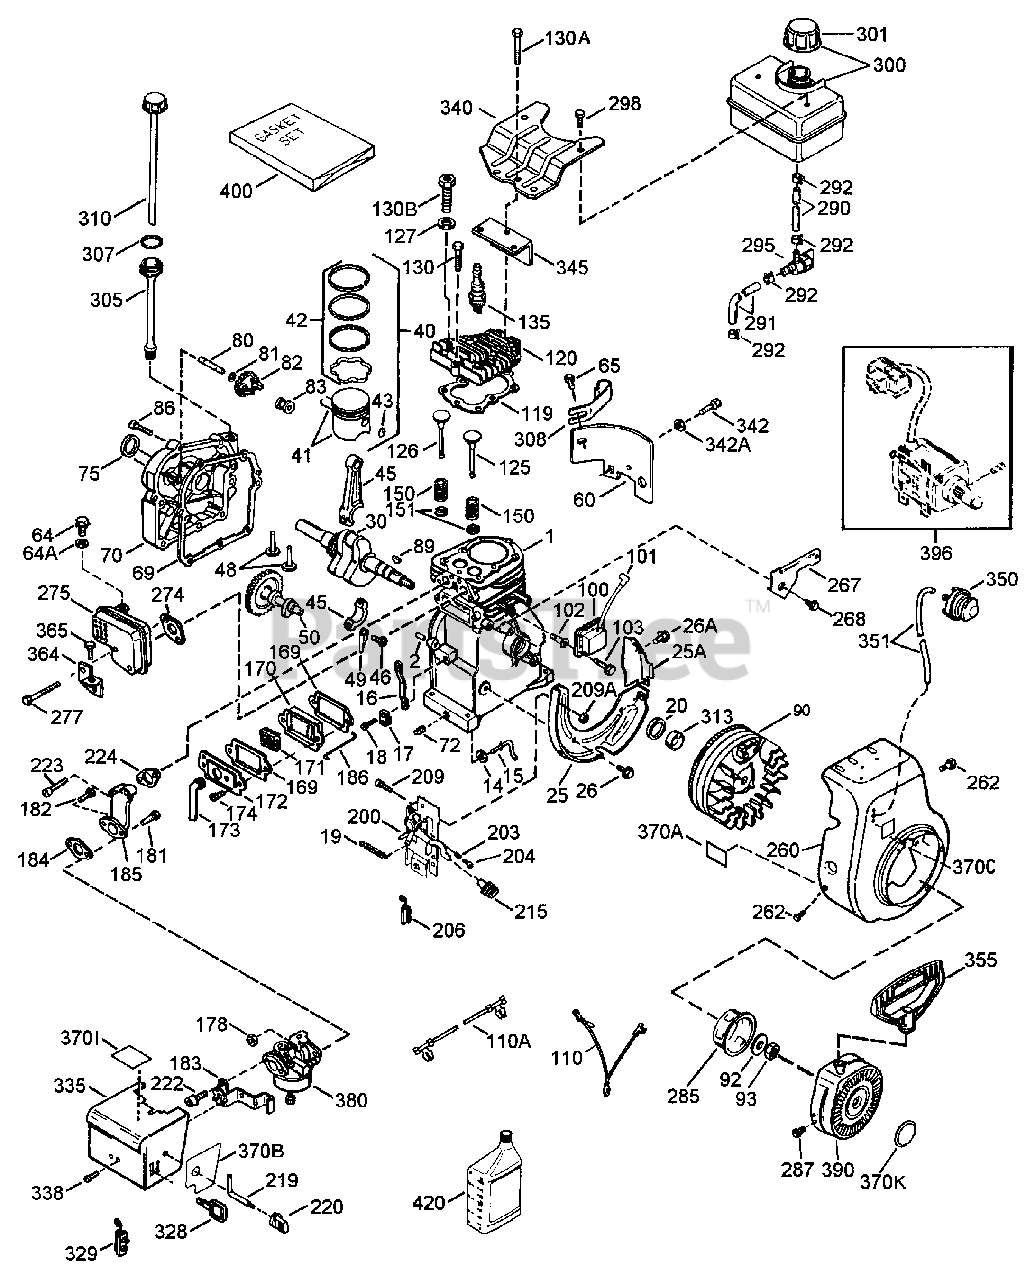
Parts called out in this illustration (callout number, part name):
1	Cylinder Assembly (Incl. Ref. #2, 20, 72 & 125)
2	Pin-Dowel
14	Washer-Flat
15	Rod-Governor
16	Lever-Governor
17	Clamp-Governor Lever
18	Screw-Torx
19	Spring-Extension
20	Seal-Oil
25	Baffle-Blower Housing
25A	Extension-Baffle
26	Screw-Hex Washer Hd.
30	Crankshaft Assembly
40	Piston-Pin & Ring Asm.. Standard
41	Piston & Pin Asm.. Standard (Incl. Ref. #43)
42	Ring Set-Piston Std.
43	Ring-Piston Pin Retaining
45	Connecting Rod Assembly (Incl. Ref. #46 & 49)
46	Bolt-Connecting Rod
48	Lifter-Valve
49	Dipper-Oil
50	Camshaft
60	Extension-Blower
64	Screw-Hex Washer Hd.
64A	Washer-Flat
65	Screw-Hex Hd.
69	Gasket-Cylinder Cover
70	Cover-Cylinder (Incl. Ref. #75 & 80)
72	Plug-Pipe
75	Seal-Oil
80	Shaft-Governor
81	Washer-Flat
82	Gear-Governor (Incl. Ref. #81)
83	Spool-Governor
86	Screw-Hex Hd.
89	Key-Flywheel
90	Flywheel-w/Ring Gear
92	Washer-Belleville
93	Nut-Flywheel
100	Solid State Assembly
101	Cover-Spark Plug
103	Screw-Torx
110	Wire-Ground
110A	Ground Wire
119	Gasket-Cylinder Head
120	Head-Cylinder (Incl. Ref. #131)
125	Valve-Exhaust Standard (Incl. Ref. #151)
126	Valve-Intake Standard (Incl. Ref. #151)
127	Washer-Flat
130	Screw-Hex Flange Hd.
130A	Screw-Hex Flange Hd.
130B	Screw-Special
135	Plug-Spark (Champion RJ-19LM or equivalent)
150	Spring-Valve
151	Cap-Valve Spring
169	Gasket-Valve Cover
170	Body-Valve Cover
171	Element-Valve Body
172	Cover-Breather
173	Tube-Breather
174	Screw-Hex Hd.
178	Nut & Lockwasher
181	Screw-Hex Hd.
182	Screw-Hex Hd.
183	Bracket-Choke
184	Gasket-Carburetor
185	Pipe-Intake
186	Link-Governor to Throttle
200	Control Assembly (Incl. Ref.# 203, 204, 206, 209 & 209A)
203	Spring-Compression
204	Screw-Fil. Hd.
206	Terminal Assembly
209A	Lock Nut
215	Knob-Speed Control
219	Rod-Choke
220	Knob-Choke Control
222	Screw-Fil. Hd.
223	Screw-Fil Hd.
224	Gasket-Intake
260	Housing-Blower
262	Screw-Hex Hd.
267	Bracket-Hold Down
268	Screw-HexWashers Hd.
274	Gasket-Exhaust
275	Muffler (Incl. Ref.# 274)
277	Screw-Fil. Hd.
285	Cup-Starter
287	Screw-HexWasher Hd.
290	Line-Fuel
291	Line-Fuel
292	Clamp-Fuel Line
295	Valve-Shut-Off
298	Screw-HexWasher Hd.
300	Tank Assembly-Fuel (Incl. Ref. #292 & 301)
301	Cap-Fuel Tank
305	Tube Asm..-Oil Fill
307	"O" Ring
308	Clip-Oil Fill
310	Dipstick
313	Spacer-Flywheel Key
328	Ignition Key
329	Terminal
335	Cover-Carburetor
338	Screw-Pan Hd.
340	Plate-Fuel Tank
342	Screww/Belleville Washer
342A	Washer-Flat
345	Baffle-Heat
350	Primer Assembly
351	Line-Primer
355	Handle-Starter
364	Carburetor Cover Bracket
370A	Decal-Lubrication
370B	Control Decal
370C	Primer Decal
370I	Warning Decal
370K	Starter Decal
380	Carburetor (Incl. Ref. #184)
390	Starter-Rewind
396	Electric Starter Kit (110 V)(Optional)
400	Gasket Set (Incl. Parts Marked )(26756 (1), 27234A (2), 27272A (1), 27677A (1), 29673 (1), 36443 (1), 33670A (1), 33673A (1)
420	Oil-4 Cycle SAE 5W30 (Quart)
